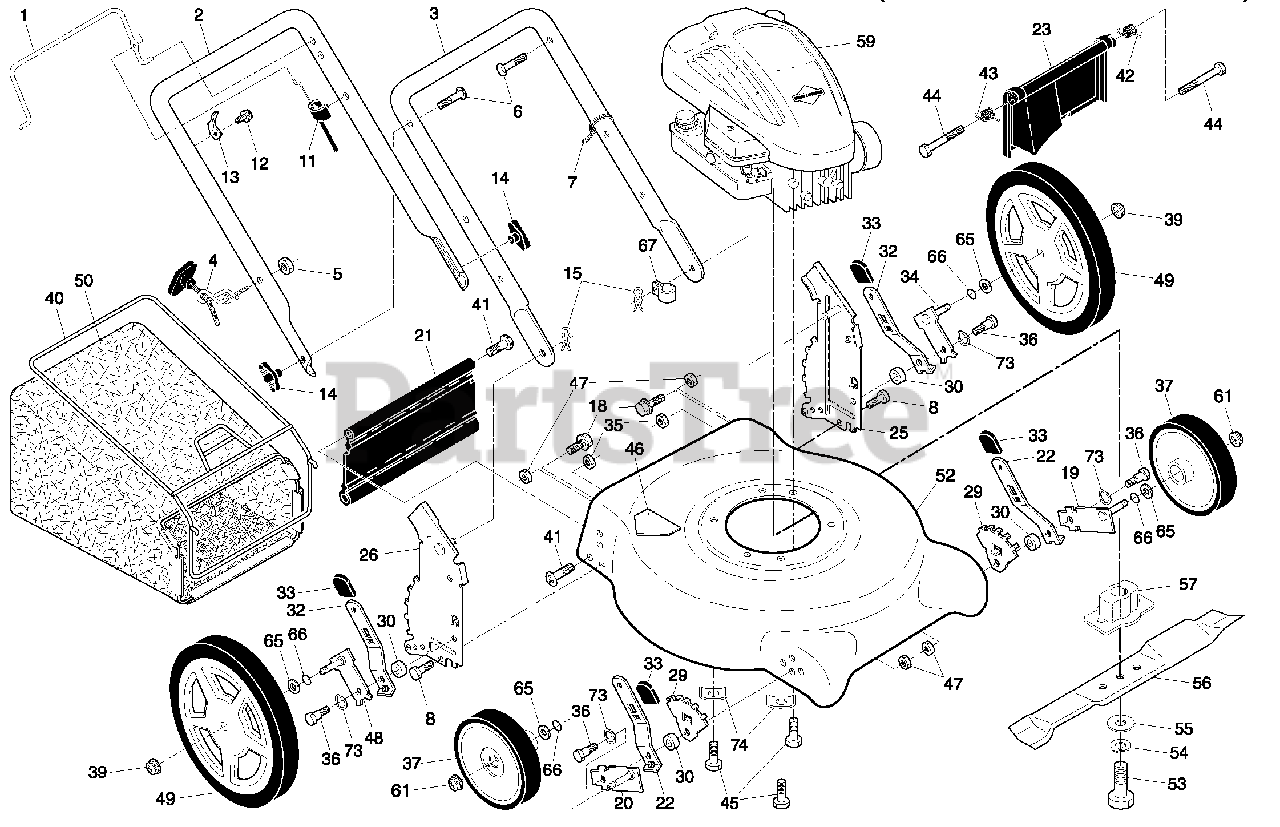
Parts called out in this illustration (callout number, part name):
1	Control Bar
2	Upper Handle
3	Lower Handle
4	Rope Guide
6	Handle Bolt
7	Wire Tie
8	Bolt, Hex Head 5/16-18 x 3/4
11	Engine Zone Control Cable
12	Hex Washer Head Screw #10-24 x 1/2
13	Up-Stop Bracket
14	Handle Knob
15	Hairpin Cotter
18	Screw
19	Axle Arm Assembly, Front, LH
20	Axle Arm Assembly, Front, RH
21	Rear Skirt
22	Selector Spring, Front
23	Rear Door Assembly
25	Handle Bracket Assembly, LH
26	Handle Bracket Assembly, RH
28	Wheel Adjusting Bracket, Front, LH
29	Wheel Adjusting Bracket, Front, RH
30	Spacer
32	Selector Spring, Rear
33	Selector Knob
34	Axle Arm Assembly, Rear, LH
35	Nut, Hex
36	Shoulder Bolt 5/16-18
37	Wheel & Tire Assembly, Front 7 x 1-3/4
39	Nut, Hex
40	Frame, Grassbag
41	Screw, Hinge
42	Spring, LH
43	Spring, RH
44	Bolt, Rear Door
45	Hex Head Thread Rolling Screw 3/8-16 x 1
46	Danger Decal
47	Locknut, Hex 5/16-18
48	Axle Arm Assembly, Rear, RH
49	Wheel & Tire Assembly, Rear 12 x 1-3/4
50	Grassbag
52	Housing Assembly
53	Hex Head Screw 3/8-24 x 1-3/8 Grade 8
54	Helical Lockwasher
55	Hardened Washer
56	21" Blade
57	Blade Adapter
61	Flanged Locknut
65	Washer, Flat
66	O-Ring
67	Clip, Cable
73	Washer, Curved, Cylindrical
74	Washer, Special, Engine
74	Operator's Manual, English
74	Operator's Manual, French
74	Repair Parts Manual
